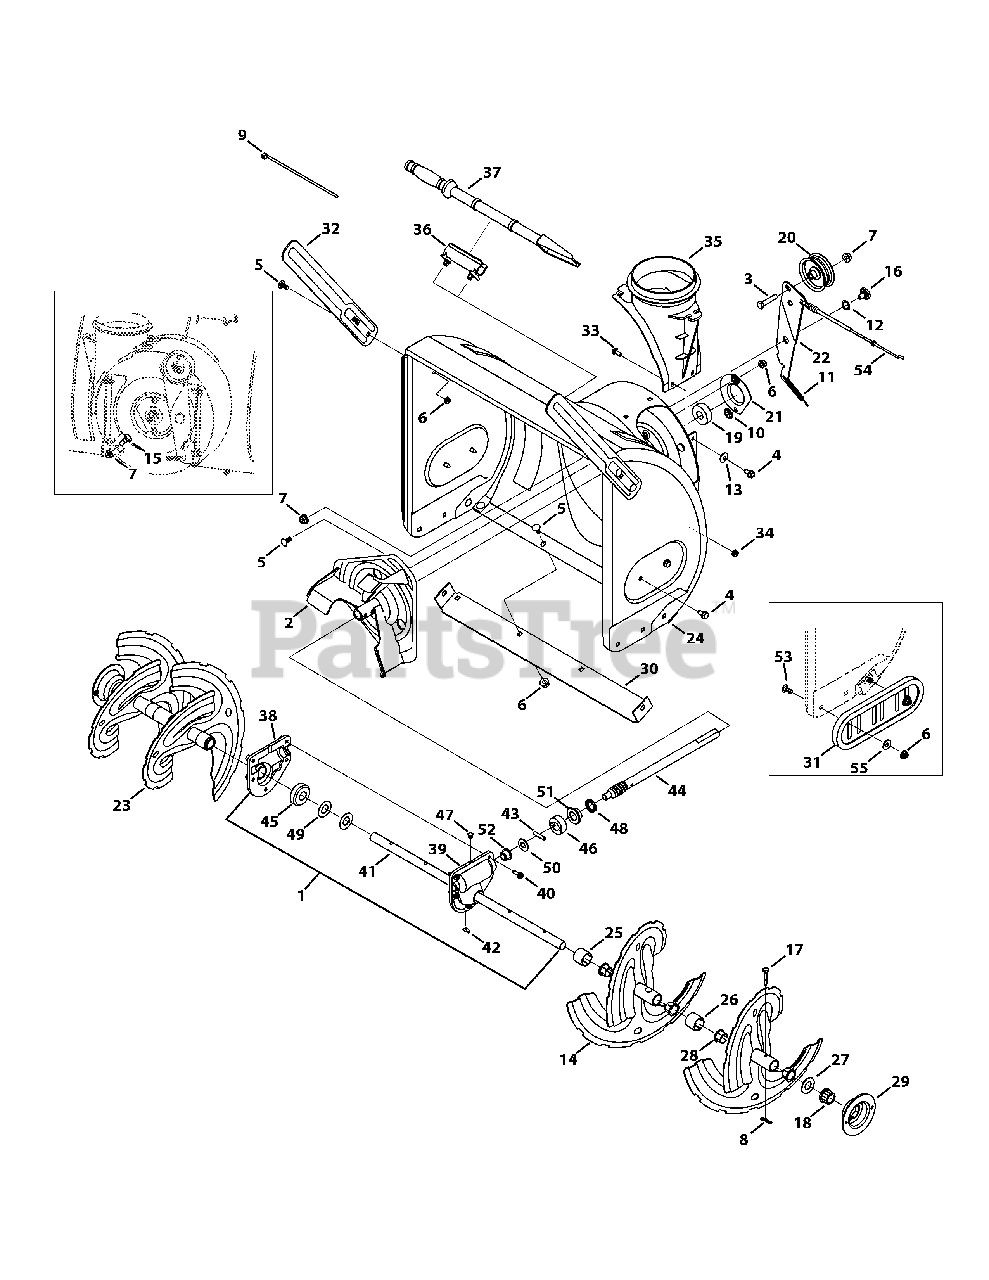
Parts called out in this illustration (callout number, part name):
1	Auger Gearbox 30", includes 38-52
2	Impeller Assembly, 12" Dia.
3	Hex Head Screw, 3/8-16 x 1.75
4	Screw, 5/16-18 x .750
5	Bolt, Carriage, 5/16-18 x .750
6	Nut, Flange lock, 5/16-18
7	Nut, Flange lock, 3/8-16
8	Bow-Tie Cotter Pin
9	Cable Tie, 7"
10	Nut, Push-on, .25 Dia.
11	Extension Spring, .38 x 4.59
12	Washer, Wave, .625 x .885
13	Washer, Bell, .340 x .872
14	Spiral Assembly, LH
15	Bolt, Shoulder, .496 x .336 x 3/8-16
16	Screw, Shoulder, .625 x .17 x 3/8-16
17	Shear Pin, .25 x 1.50
18	Bearing, Hex Flange, .75
19	Bearing, Ball, .75 x 1.85
20	Pulley, Idler, Flat, 2.75
21	Bearing, 1.85 ID
22	Auger Idler Bracket
23	Spiral Assembly, RH
24	Auger Housing Assembly
25	Spacer, 1.25 x .75 x 1.00
26	Spacer, 1.25 x .75 x 2.00
27	Washer, Flat, .76 x 1.49
28	Bushing, Flange, .800 x .910
29	Bearing, 1" Hex
30	Shave Plate, 2.25 x 29.66
31	Polymer Slide Shoe
31	Polymer Reversible Shoe Kit
32	Blade Guide
33	Screw, Carriage, 1/4-20 x .75
34	Nut, Flange lock, 1/4-20
35	Chute Adapter
36	Clean-Out Tool Mount
37	Clean-Out Tool
38	Reducer, RH
39	Reducer, LH
40	Screw, 1/4-20 x 0.750
41	Auger Axle, 30"
42	Key, Hi-Pro, 3/16 x 5/8
43	Dowel Pin, .25 x 1.25
44	Worm Shaft, .75
45	Gear Worm, 20T
46	Collar Thrust, .756 x .600
47	Plug, 1/4 x .437
48	Oil Seal, .75 x 1.131 x .188
49	Washer, Flat, .760 x 1.50
50	Washer, Flat, .51 x 1.12
51	Bearing, Flange, .75 x 1.00 x .59
52	Bearing, Flange, .50 x .75 x .59
53	Screw, Carriage, 5/16-18 x 1.00
54	Auger Drive Clutch Cable
55	Washer, Flat, .349 x .879 x .063
